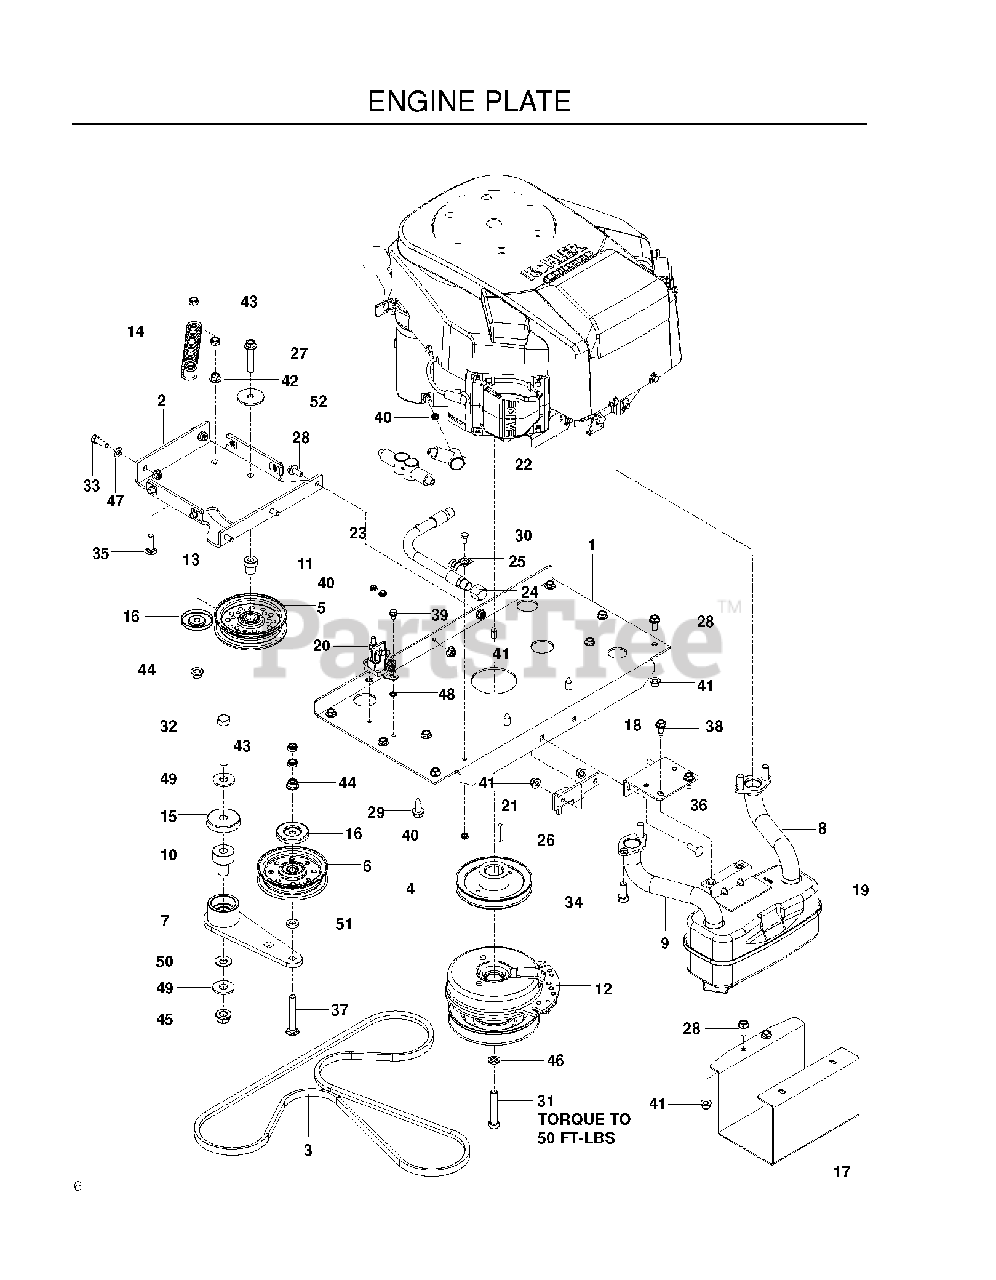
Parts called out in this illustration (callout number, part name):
2	PLATE, IDLER, BLK
3	BELT, HYDRO, 3400
4	PULLEY, V, 1.125 BORE
5	IDLER PULLEY
7	ARM, IDLER, STEEL, W/BGS
8	PIPE-EXHAUST LH
9	PIPE-EXHAUST RH
10	PIVOT, BEARING
11	PIVOT, IDLER
12	CLUTCH, 200 FT-LB
13	U-CLIP 5/16-18 NUT RETAINER
14	SPRING, PUMP
15	SHIELD, DUST
16	DUST SHIELD
19	MUFFLER ASM TWIN
20	SOLENOID
22	INSULATOR
23	OIL DRAIN HOSE
24	DRAIN CAP
26	KEY, 1/4 SQ X 1 1/4
27	HHFS 3/8-16 X 2.0 GD 5
28	HHFS 5/16-18 X 3/4
29	HHFS 3/8-16 X 1.0 THD FORMING
30	HCS 1/4-20.
31	BOLT 7/16F X 2 1/2
32	HCS 1/2C X 3 1/4
33	HCS 5/16C X 1
34	HCS 5/16C X 3/4
35	RHSNB 3/8-16 X 1-1/4
36	RHSSNB 5/16C X 1.0
37	RHSNB 3/8-16 X 2.75
38	BOLT 5/16-18 X 3/4
39	HWST 1/4C X 3/8
40	JAM NUT 1/4C
41	5/16-18 NYLOC FLANGE NUT
42	NUT 3/8C WHIZ
43	NUT HEX 3/8-16 NYLON, THIN
44	NUT 3/8-16 HEX FLG NYLOC ZD
45	NUT, 1/2-13 HEX FLG NYLOC ZD
46	WASHER 7/16 LOCK
47	FLAT WASHER 5/16 SAE
48	WASHER 1/4 INT TOOTH
49	WASH USS FLAT 1/2
50	CONTACT BELLSPR 1/2
51	WASHER 3/8 X 3/4 X .187 TK
52	WASHER, 3/8 SPEC
